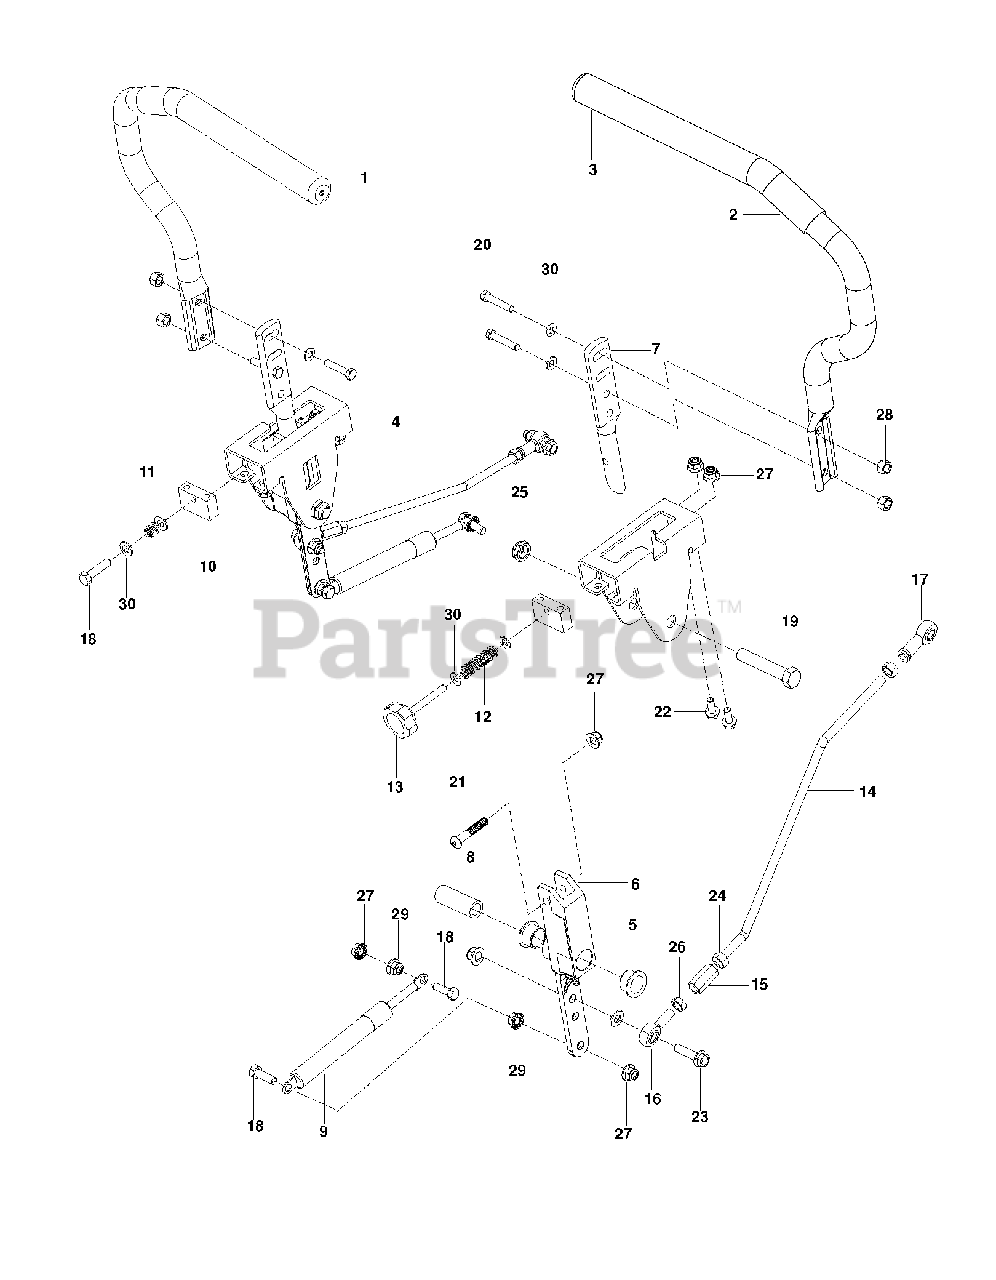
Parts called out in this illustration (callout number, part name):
1	LEVER.DRIVE.W/GRIP.RIGHT
2	LEVER.DRIVE.W/GRIP.LEFT
3	GRIP - DRIVE LEVER 12"
4	BRACKET, CONTROL
5	BEARING, FLANGE
6	LEVER CONTROL PIVOT
7	LEVER.HANDLE MOUNT
8	SPACER, PIVOT CONTROL
10	BLOCK.TRACKING
12	SPRING COMPRESSION 2.0
14	ROD, CONTROL
15	ROD END COUPLER
16	RB ROD.END.LH
17	RH ROD END
18	HCS 5/16C X 1 1/4
19	HCS 1/2C X 2 3/4
20	CAPSCREW 5/16 X 1/1/2 HEX HEAD
21	SCREW 5/16-18 X 1 3/4 BTN-HD
22	HHFS 5/16-18 X 3/4
23	HHFS 5/16-18 X 1.25 TPBLT GD 5
25	NUT 1/2-13 HEX JM NYL
26	NUT 5/16F LEFTHAND
27	5/16-18 NYLOC FLANGE NUT
28	NUT 5/16 NYLOC
29	NUT 5/16C WHIZ
30	FLAT WASHER 5/16 SAE
